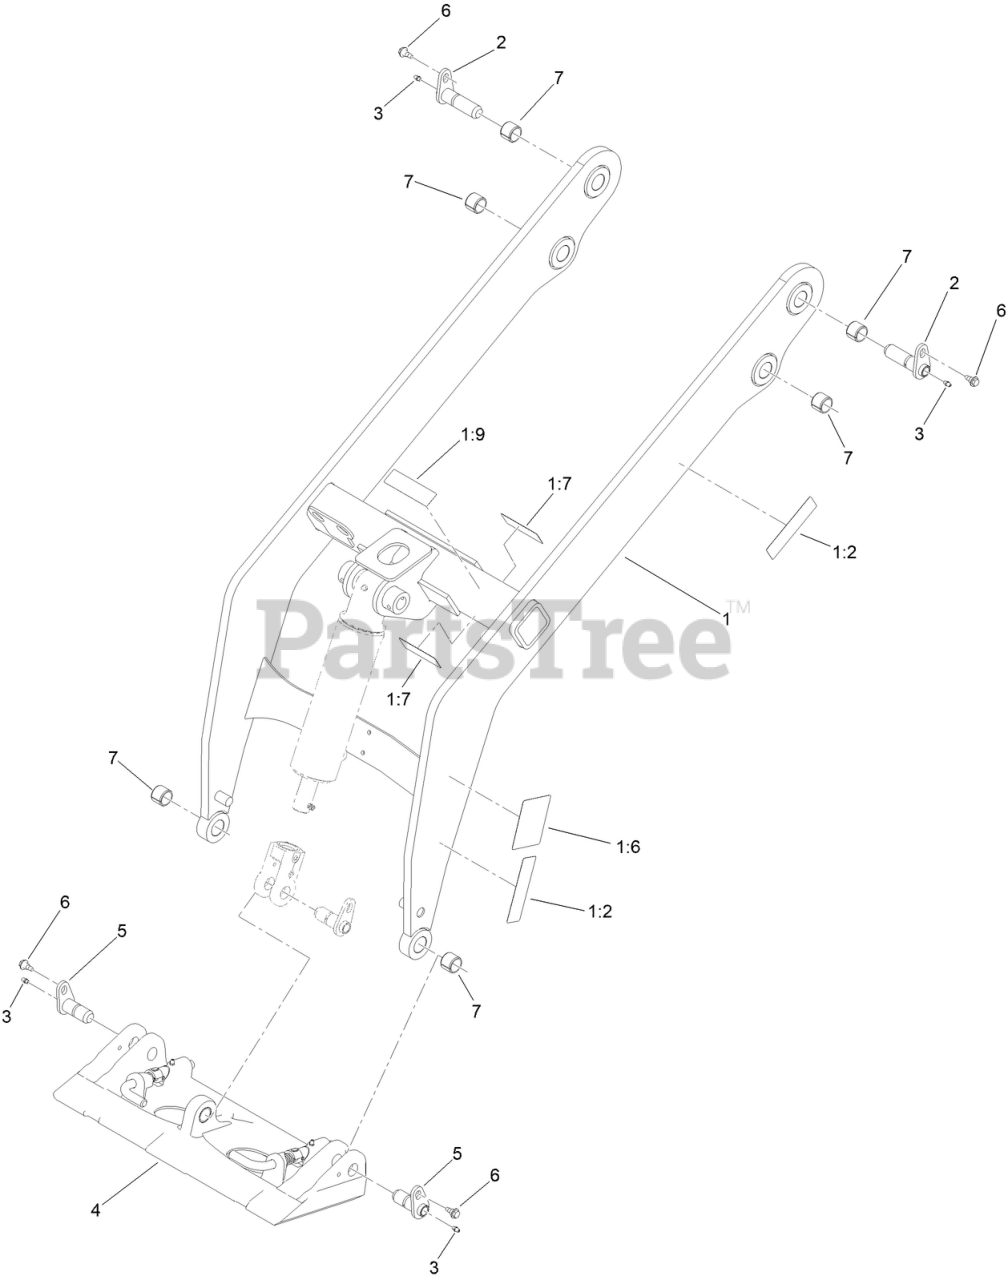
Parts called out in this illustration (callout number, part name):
1	LOADER AND DECAL ASM
1:2	DECAL-WARNING, CRUSHING
1:6	DECAL-WARNING, BUCKET
1:7	DECAL-WARNING, NO RIDER
1:9	DECAL-CAUTION
2	PIN-PIVOT
3	FITTING-GREASE
4	QUICK ATTACH ASM
5	PIN-PIVOT
6	BOLT-SHOULDER
7	BUSHING-TENSION
